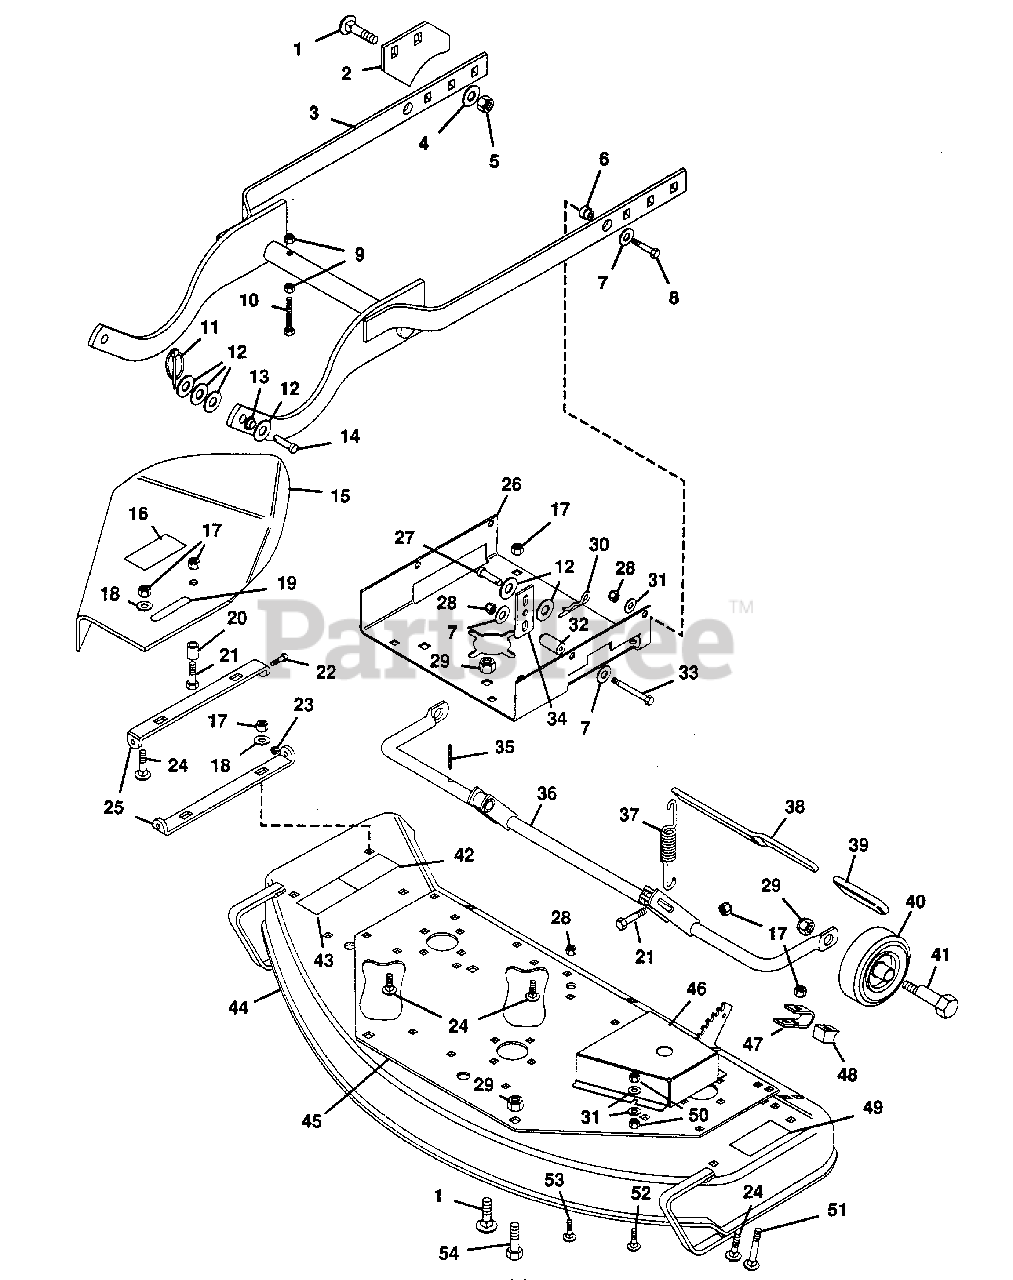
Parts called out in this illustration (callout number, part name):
1	Bolt, Carriage 1/2-13x1.25
2	Plate, Cam
3	Weldment, Drag Arm
4	Washer, Flat .531x1.250x.100
5	Nut, Lock 1/2-13
6	Bush., Flg. .344x1.00x.670 Stl.
7	Washer, Flat .375x1.125x.065
8	Bolt, Hex 5/16-18x1.375
9	Nut, Lock 5/16-18
10	Bolt, 5/16-18x2.50 All Thread
11	Pin, Klik
12	Washer, Flat .531x1.063x.095
13	Bush., Flg. .512x.750x.459 Ny.
14	Pin, Clevis .50x1.330
15	Shield, Safety Ext. 50" Mower
16	Decal, Caution
17	Nut, Lock 3/8-16
18	Washer, Flat .406x.812x.065
19	Decal, Width of Cut
20	Stop, Chute
21	Bolt, Hex 3/8-16x1.50
22	Bolt, Hex 1/4-20x.875
23	Nut, Lock 1/4-20
24	Bolt, 3/8-16x1 Rd Hd Sq Nk
25	Bracket, Chute
26	Channel, 50" GEM
27	Pin, Clevis .50x.875
28	Nut, Lock 5/16-18
29	Nut, Lock 1/2-13
30	Pin, Cotter Hair
31	Washer, Flat .344x.688x.065
32	Bushing, Link
33	Bolt, Hex 5/16-18x2.50
34	Link
35	Pin, Cotter .125x1.25
36	Weldment, Axle
37	Spring, 40 and 50 Inch Mower
38	Lever, Height of Cut
39	Grip, Handle
40	Wheel, Gauge
41	Bolt, Eccentric
42	Decal, Warning Eye
43	Decal, Danger Hand
44	Weldment, 50" Deck
45	Plate, Support
46	Cover, Belt L.H.
46	Cover, Belt R.H.
47	Bracket, Axle Support
48	Stop, Nylon
49	Decal, Danger Foot
50	Nut, Jam 5/16-18 Hex
51	Bolt, 3/8-16x2 Rd Hd Sq Nk
52	Bolt, Carriage 5/16-18x1.00
53	Bolt, Carriage 5/16-18x.75
54	Bolt, Hex 1/2-13x1.00
